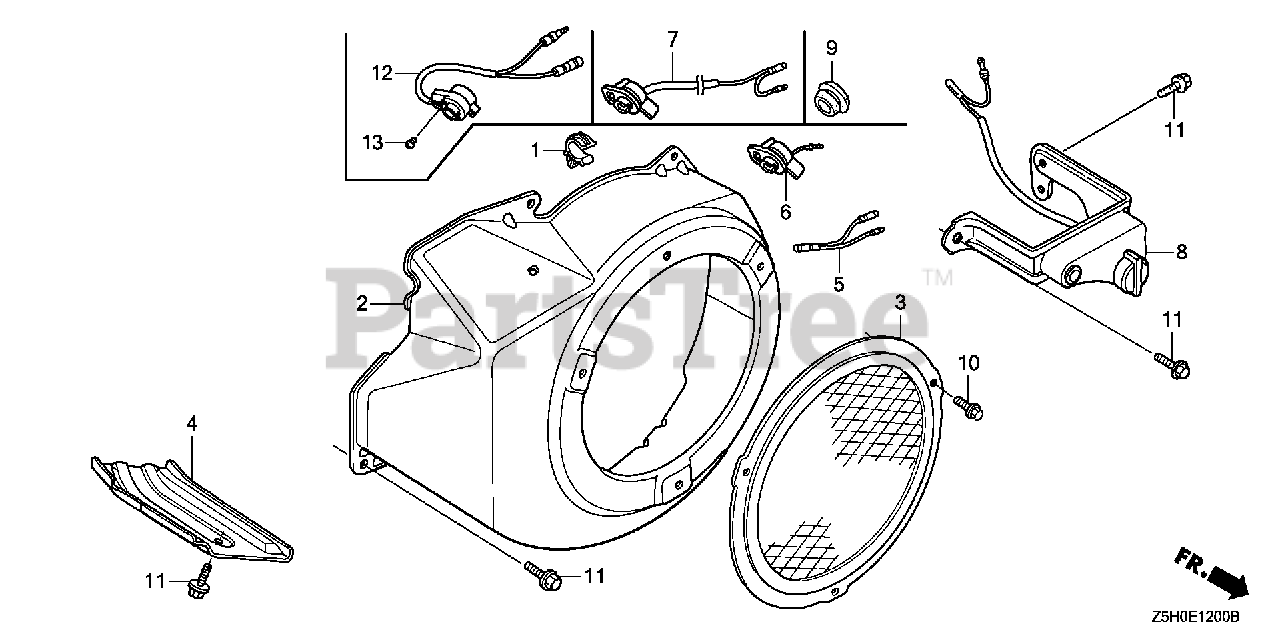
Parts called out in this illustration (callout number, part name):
1	CLIP, TUBE
2	COVER, FAN *NH1* (BLACK)
2	COVER, FAN *NH246* (LOOSY GRAY)
2	COVER, FAN *R280* (Honda Code 7323561). (POWER RED)
4	SHROUD
7	SWITCH ASSY., ENGINE STOP
11	BOLT, FLANGE (6X12) (CT200)
